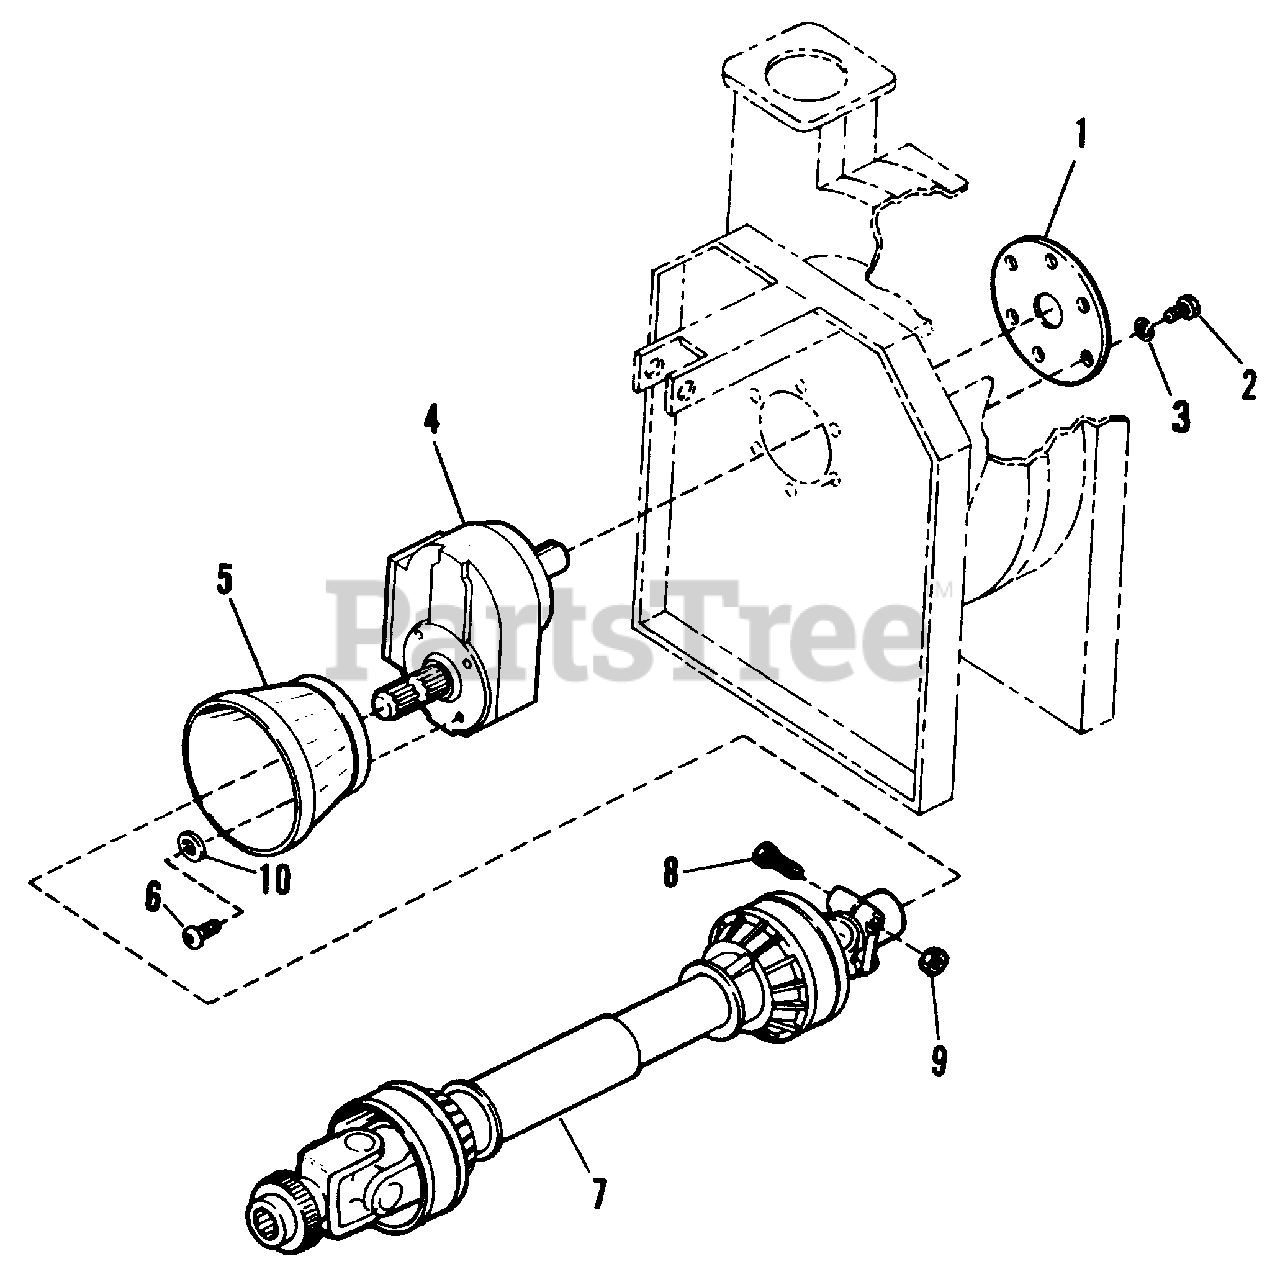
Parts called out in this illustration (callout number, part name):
1	SEAL GUARD, PTO
2	CAPSCREW, 10 mm x 1-1/2 x 25 mm
3	LOCKWASHER, 7/16
5	SAFETY CONE
6	SCREW, Button Hd., 3/8-16 x 3/4
7	PTO DRIVELINE, w/SB2 Torque Limiter
8	BOLT, Shear, M06-1.00 x 40mm
9	NUT, Hex, Lock, Nyloc, M06-1.00
10	WASHER, Flat, 1/2
